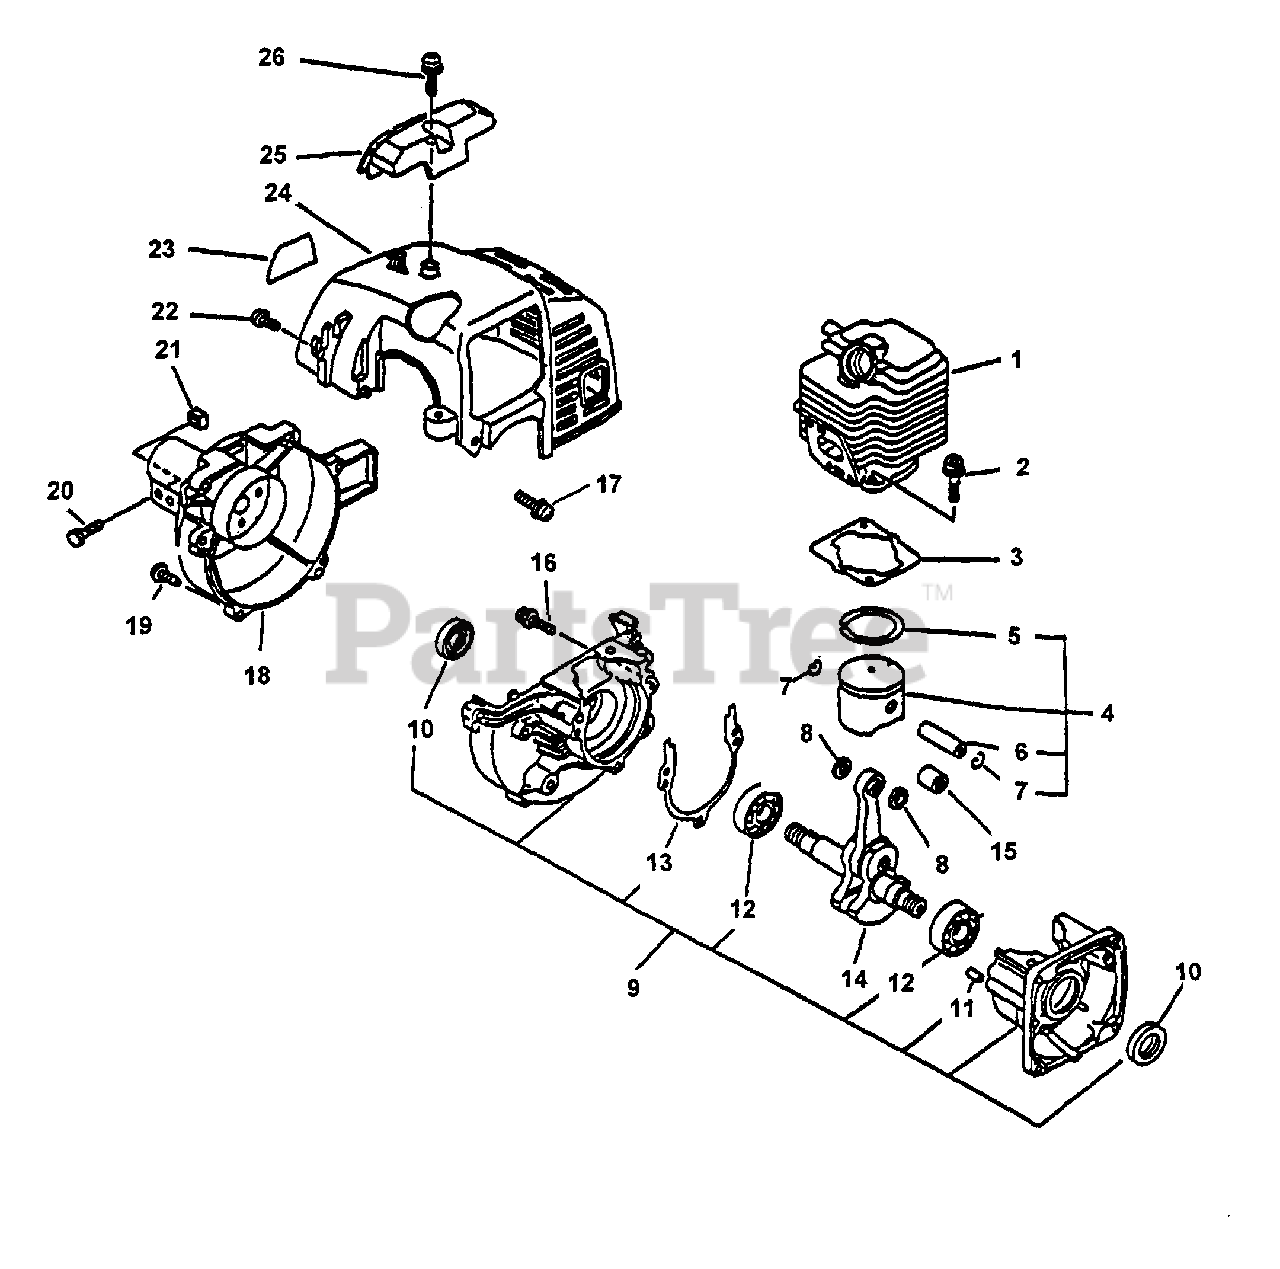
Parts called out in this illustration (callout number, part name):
1	CYLINDER
2	BOLT 5×22
3	GASKET, CYLINDER
4	PISTON KIT
5	RING, PISTON
6	PIN, PISTON 8
7	RING, SNAP
8	WASHER, THRUST
9	CRANKCASE KIT
10	SEAL, OIL 12
11	PIN, LOCATING 4
12	BEARING, BALL - 6201 C3
13	GASKET, CRANKCASE
14	CRANKSHAFT ASSY
15	CRANKSHAFT ASSY
15	BEARING, NEEDLE
16	BOLT 5×28
17	SCREW 4×12
18	FAN CASE ASSY
19	SCREW - 4×18
20	BOLT 5×28
21	NUT M5
22	BOLT 4×16
23	LABEL, PE-2000
24	COVER, ENGINE - GRAY
25	GUARD, TOP - GRAY
26	SCREW 5×16
